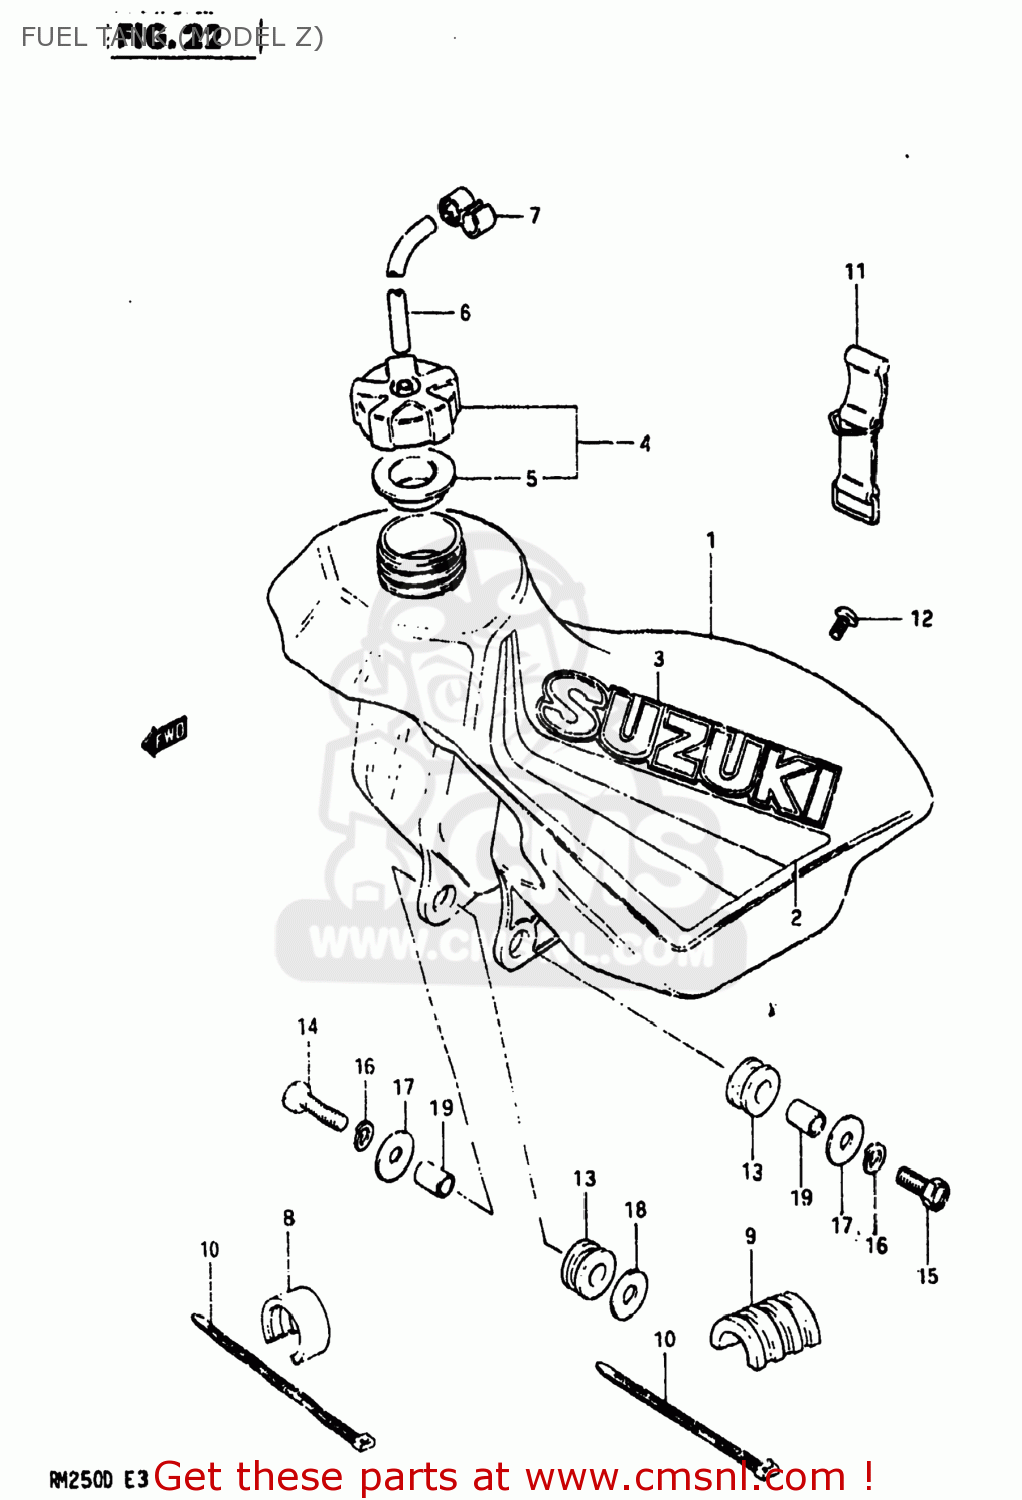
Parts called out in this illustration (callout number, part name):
1	TANK ASSEMBLY,FUEL
2	TAPE SET,FUEL TANK
3	EMBLEM
4	CAP SET,FUEL TANK
5	GASKET,FUEL TANK CAP (NAS)
6	HOSE
7	CLAMP,BREATHER HOSE
8	CUSHION,FUEL TANK UPR FR
9	CUSHION,FUEL TANK,UPPER
10	CLAMP
11	BAND
12	SCREW (6X15)
13	CUSHION
14	BOLT 8X45
15	BOLT
16	LOCK WASHER
17	WASHER
18	WASHER(8.5X26X1.2)
19	SPACER (8.8X12X13.5)
